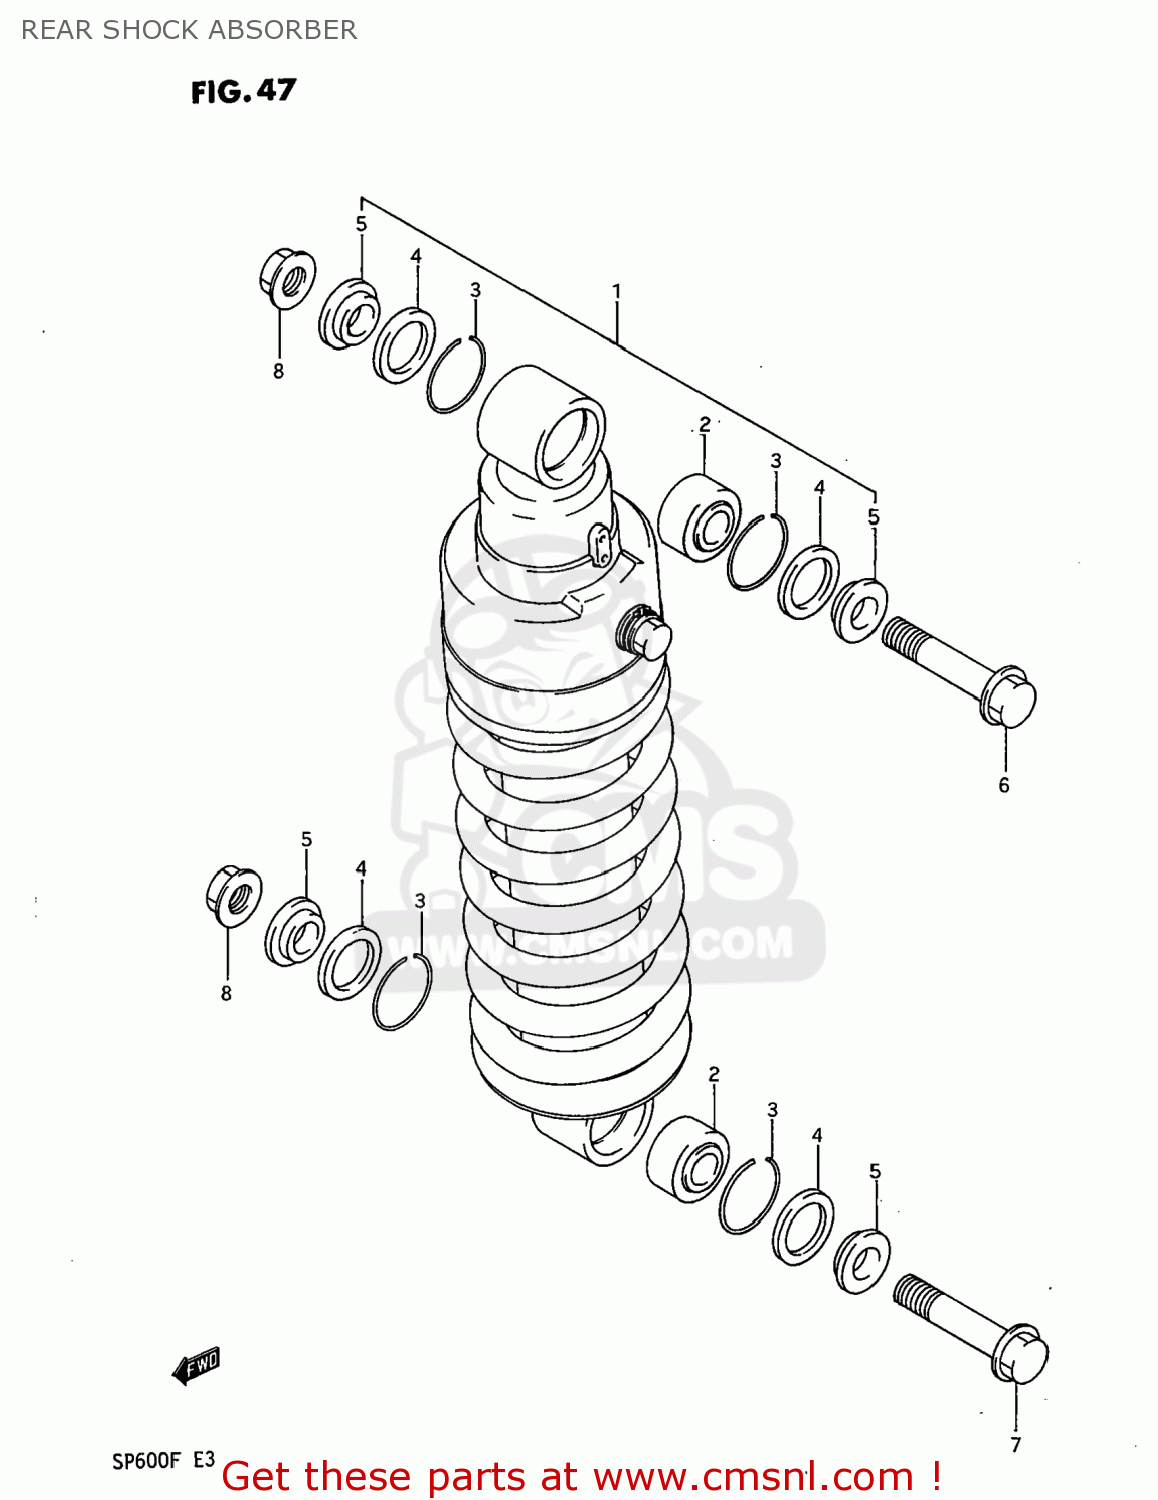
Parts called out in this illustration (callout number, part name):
1	ABSORBER ASSEMBLY,REAR SHOCK
2	BEARING,REAR SHOCK ABSORBER
3	RING
4	SEAL,DUST
5	SPACER
6	BOLT(10X54)
7	BOLT(10X52)
8	NUT
